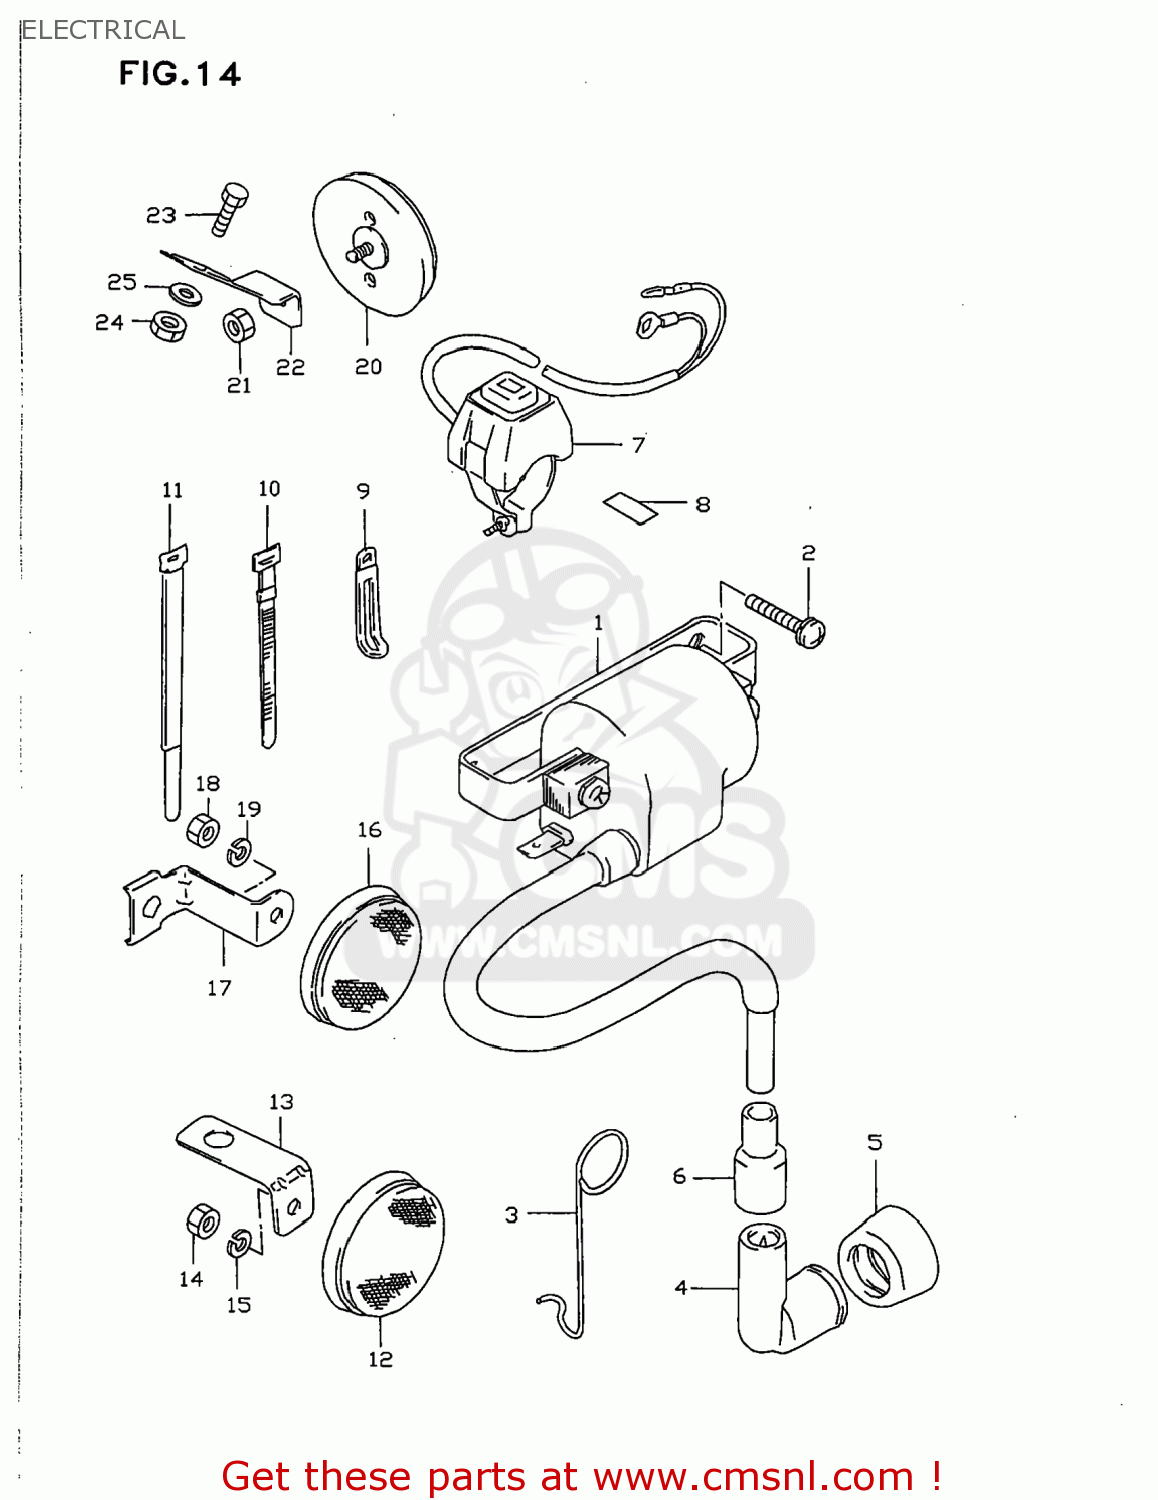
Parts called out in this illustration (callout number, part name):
1	UNIT & COIL ASSY,IGNITION
2	SCREW
3	CLIP
4	CAP ASSY,SPARK PLUG
5	SEAL,SPARK PLUG
6	SEAL,HIGH TENSION CORD
7	SWITCH ASSY,ENGINE STOP
8	LABEL (ENGINE STOP)
9	CLAMP(L:45)
10	CLAMP(L:120)
11	CLAMP
12	REFLEX REFLECTOR,FR
13	BRACKET, FR SIDE RR
14	NUT
15	LOCK,WASHER
16	REFLEX REFLECTOR,RR
17	BRACKET, NEAR SIDE RR
18	NUT
19	LOCK,WASHER
20	REFLEX REFLECTOR,RR
21	NUT
22	BRACKET, NEAR RR
23	BOLT
24	NUT 6MM
25	WASHER
